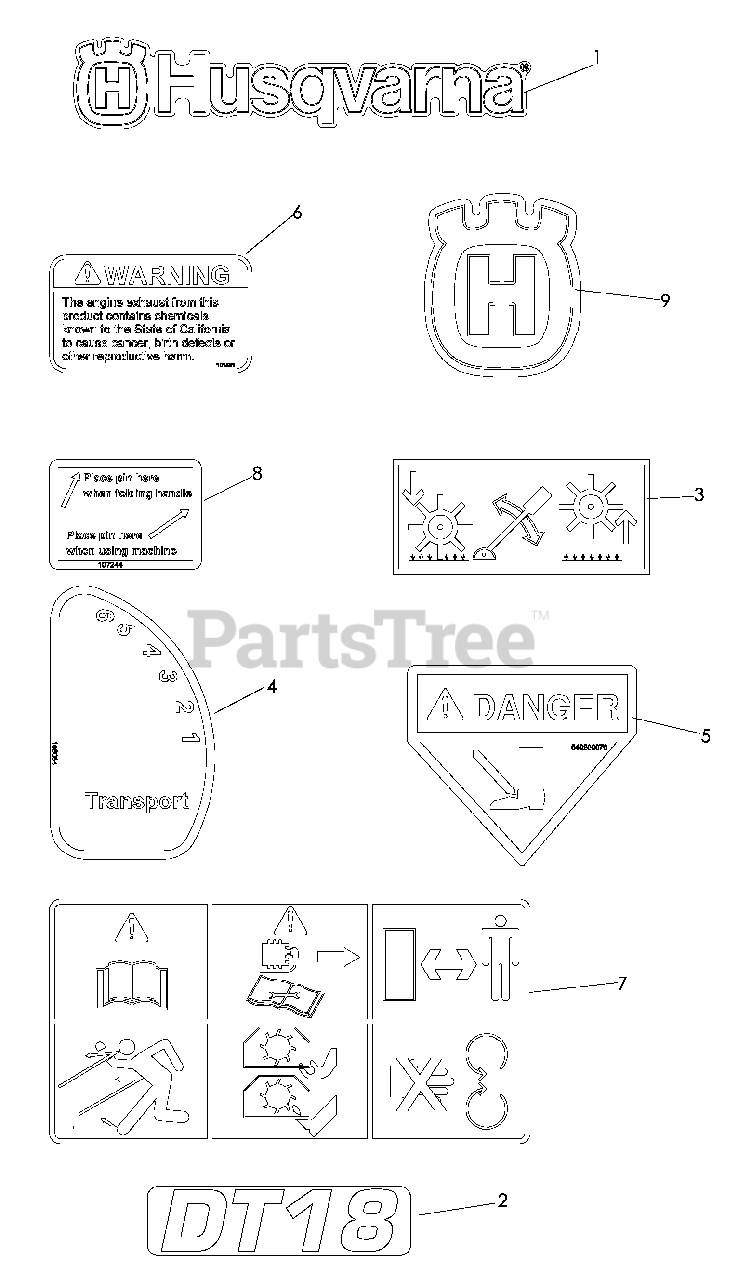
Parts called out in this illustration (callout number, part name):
1	DECAL, HUSQVARNA
2	DECAL, DT18
3	DECAL, HEIGHT ADJUST
4	DECAL, DEPTH
5	DECAL, DANGER FOOT
6	DECAL, PROP 65
7	DECAL, SAFETY GRAPHICS
8	DECAL, HANDLE PIN
9	DECAL, CROWN
